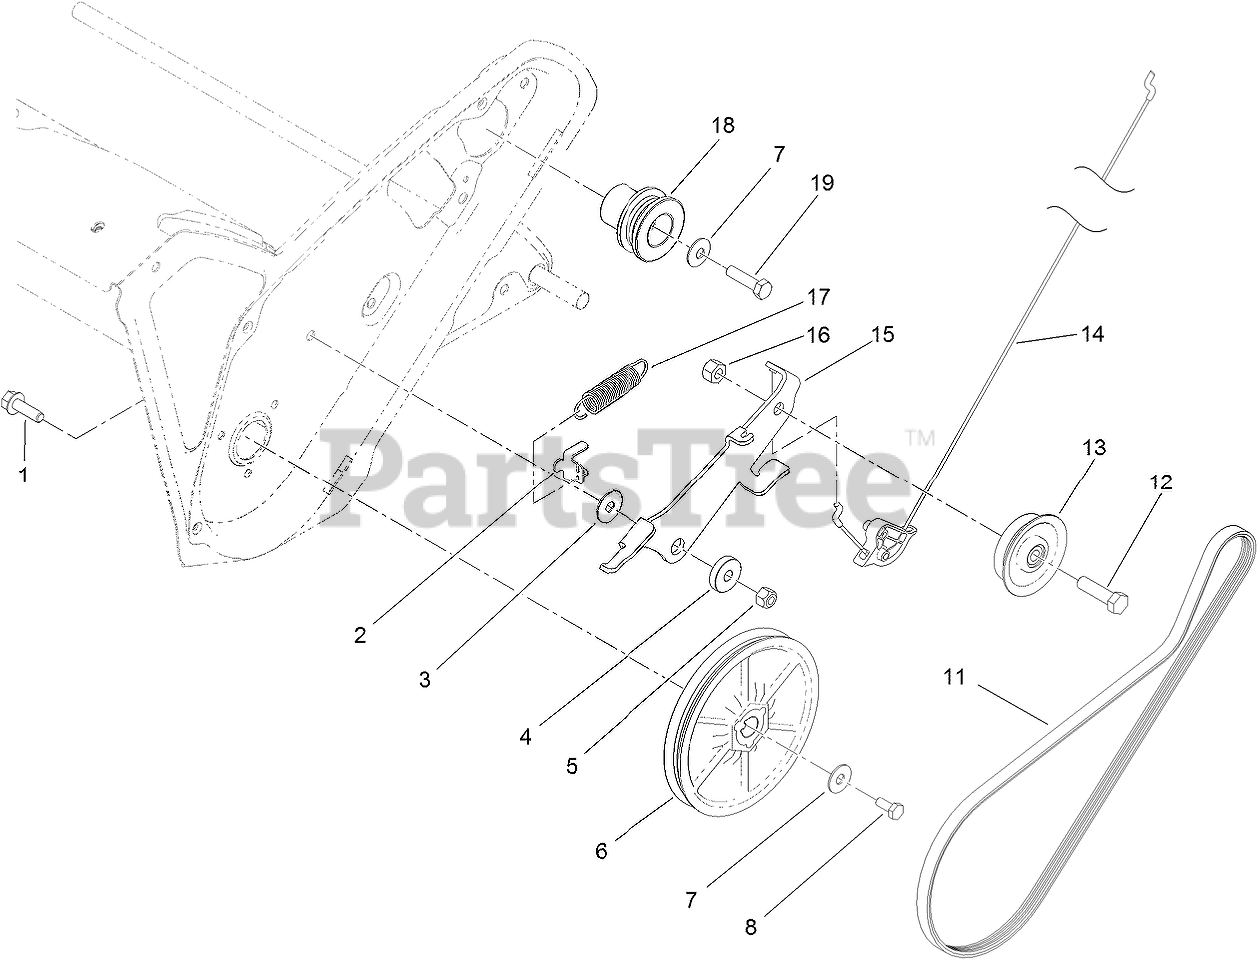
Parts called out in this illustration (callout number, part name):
1	SCREW-HHF
2	CLIP-SPRING, BRAKE
3	WASHER
4	BUSHING-PIVOT
5	NUT-LOCK, NI
6	ROTOR PULLEY ASM
7	WASHER-BELLEVILLE
8	SCREW-HH
11	BELT-DRIVE
12	SCREW-HH
13	PULLEY-IDLER
14	CABLE-CLUTCH
15	ARM-IDLER
16	NUT-LOCK, CONE
17	SPRING-EXTENSION
18	PULLEY-ENGINE
19	SCREW-HH
